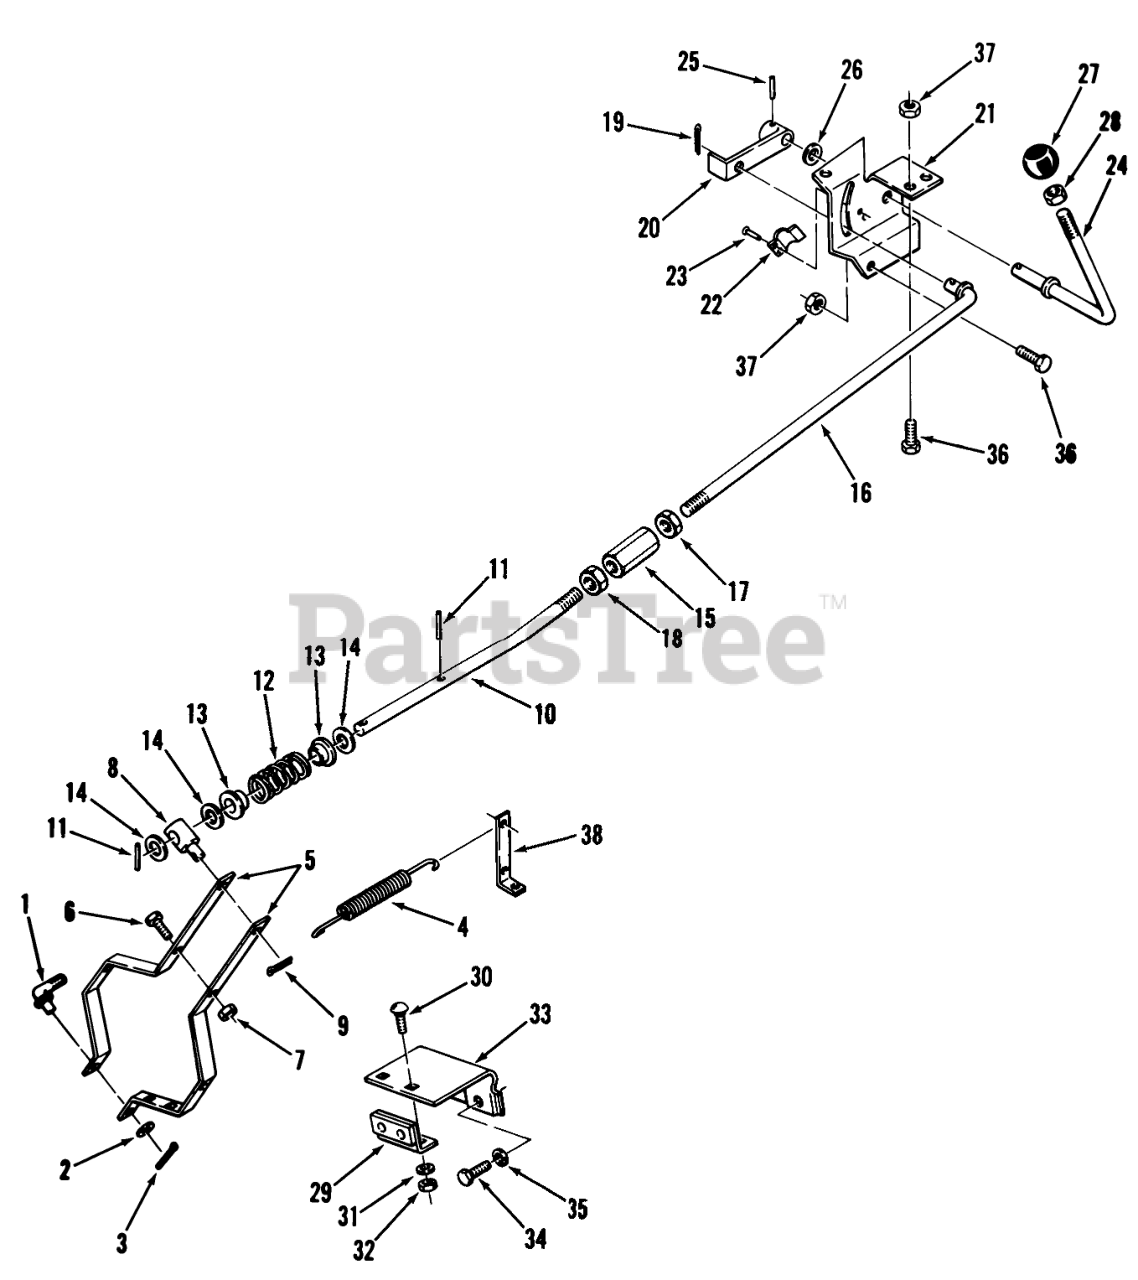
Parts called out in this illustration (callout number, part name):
2	WASHER
8	TRUNION
11	PIN-ROLL
13	BUSHING
20	ARM CLUTCH ENGAGE
23	RIVET -4
24	ASSY CLUTCH HANDLE
25	Spirol Pin
35	LOCKWASHER
